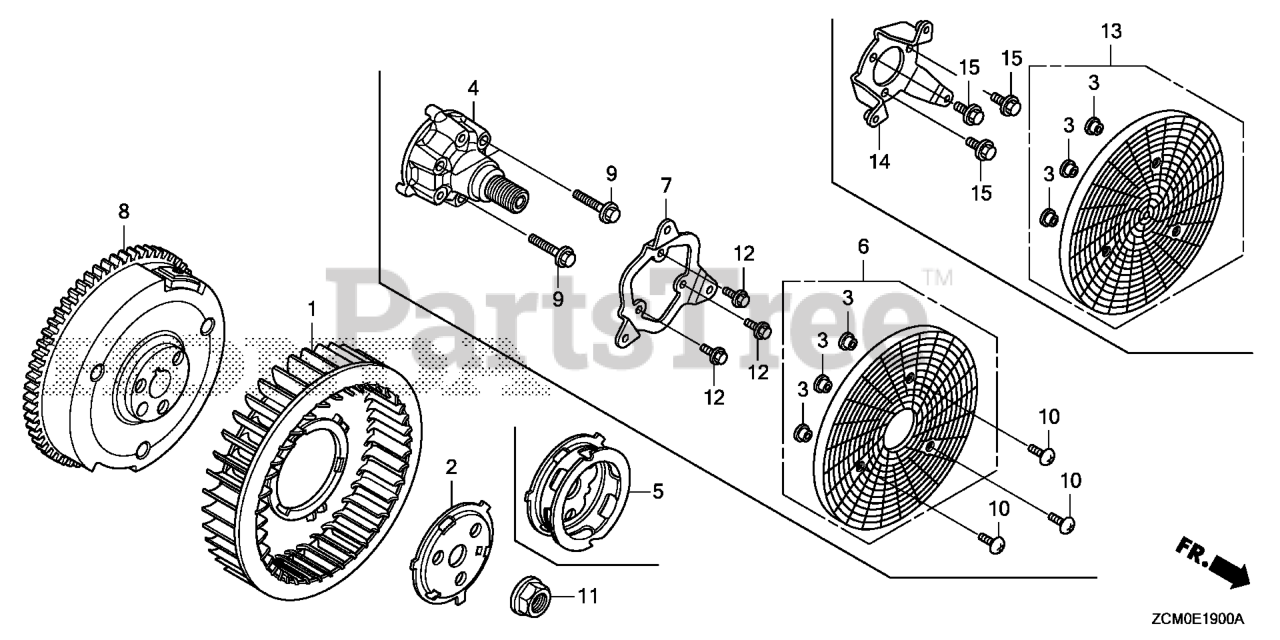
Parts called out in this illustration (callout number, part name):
1	FAN, COOLING
2	PLATE, COOLING FAN SETTING
11	NUT, SPECIAL (20MM)
